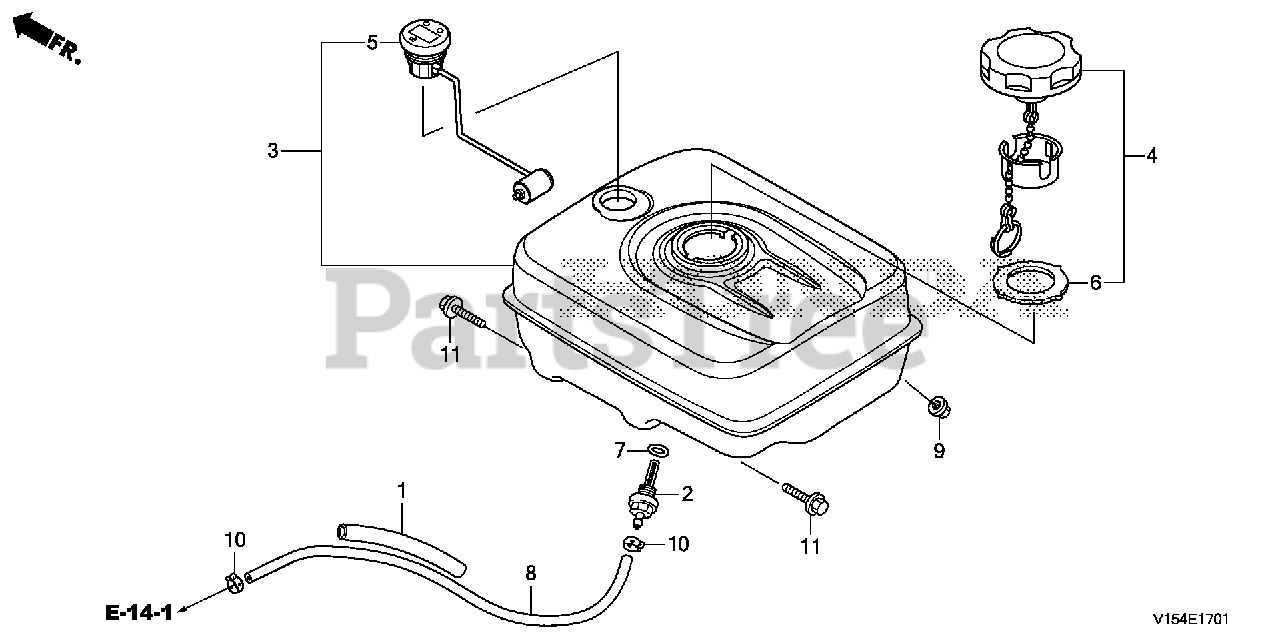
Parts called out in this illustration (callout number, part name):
1	RUBBER, SUPPORTER (107MM)
2	JOINT, FUEL TANK
3	TANK ASSY., FUEL *R280* (GAUGE) (POWER RED)
4	CAP, FUEL FILLER
5	GAUGE ASSY., FUEL
6	GASKET, FUEL FILLER CAP
7	O-RING (14MM) (ARAI) Use up to Engine SN 2949254.
7	O-RING (14MM) (NOK)
8	TUBE, FUEL (4.5X235) (FKM)
9	NUT, FLANGE (8MM)
10	CLIP, TUBE (D8)
11	BOLT, FLANGE (8X28)
